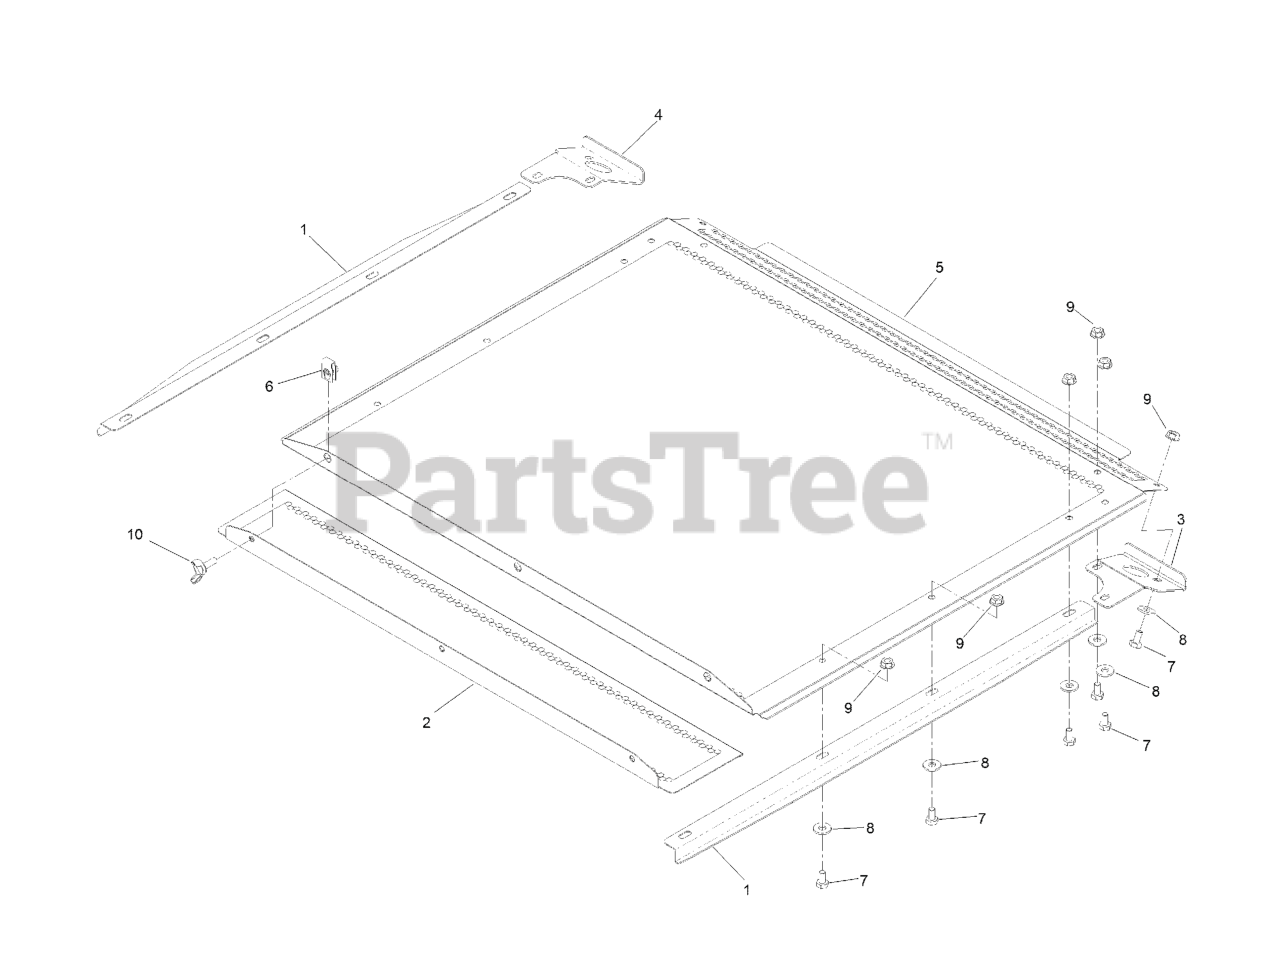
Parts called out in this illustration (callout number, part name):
1	GUIDE-SCREEN
2	PANEL-SCREEN, REMOVABLE
3	HANDLE-SCREEN, LH
4	HANDLE-SCREEN, RH
5	PANEL-SCREEN, HOPPER
7	SCREW-HH
8	WASHER-FLAT
10	SCREW-WING
